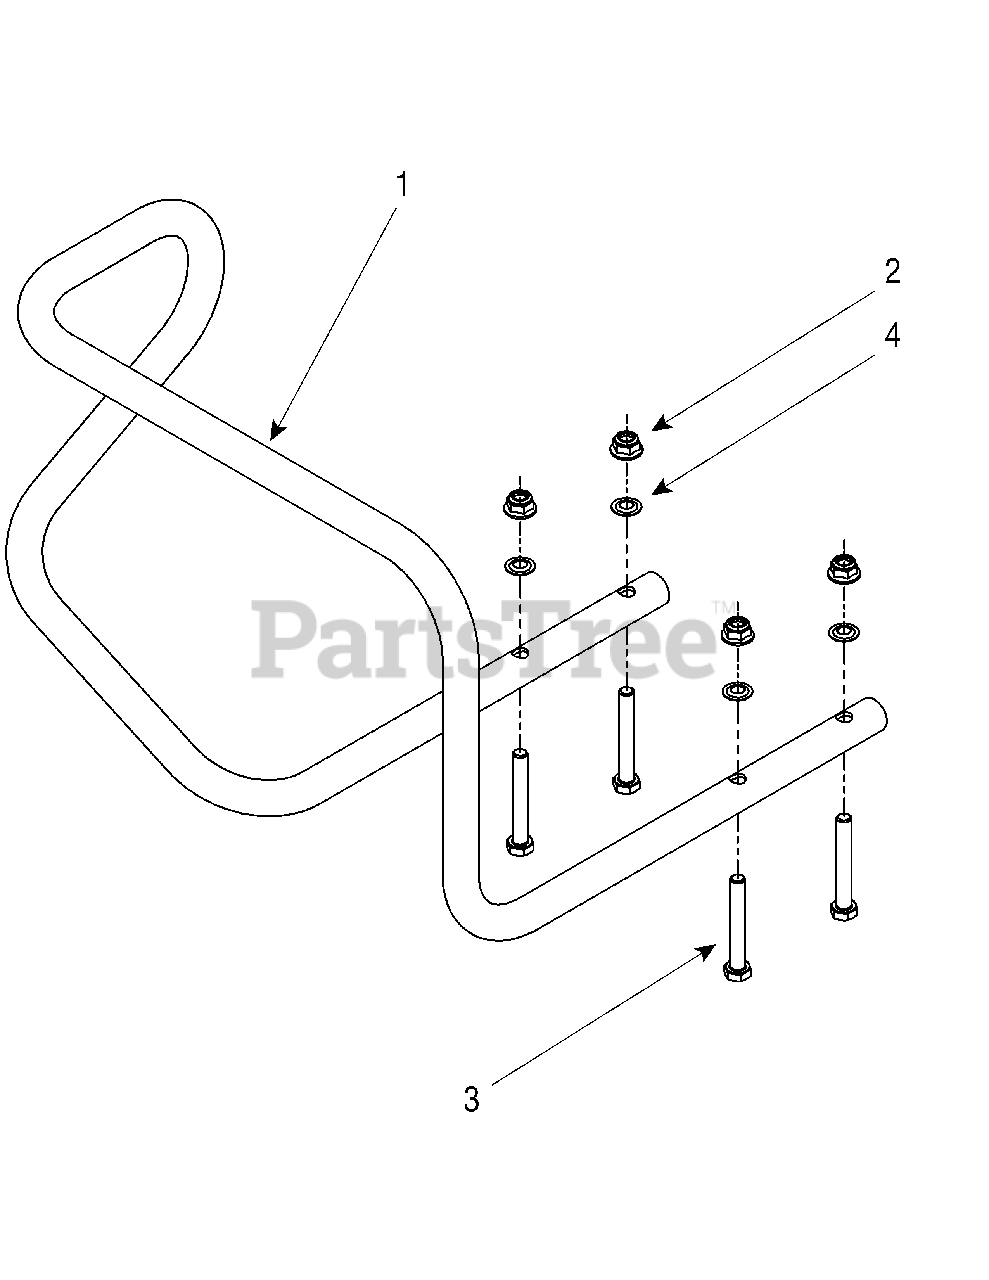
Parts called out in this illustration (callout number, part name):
2	Lock Nut-Hex, Nylon, 5/16-18 (specify Grade 5 if ordering part locally)
3	Screw-hex hd., 5/16-18 x 2 1/4
4	Lockwasher-5/16
5	Lock Nut-Hex, Nylon, 5/16-18 (specify Grade 5 if ordering part locally)
